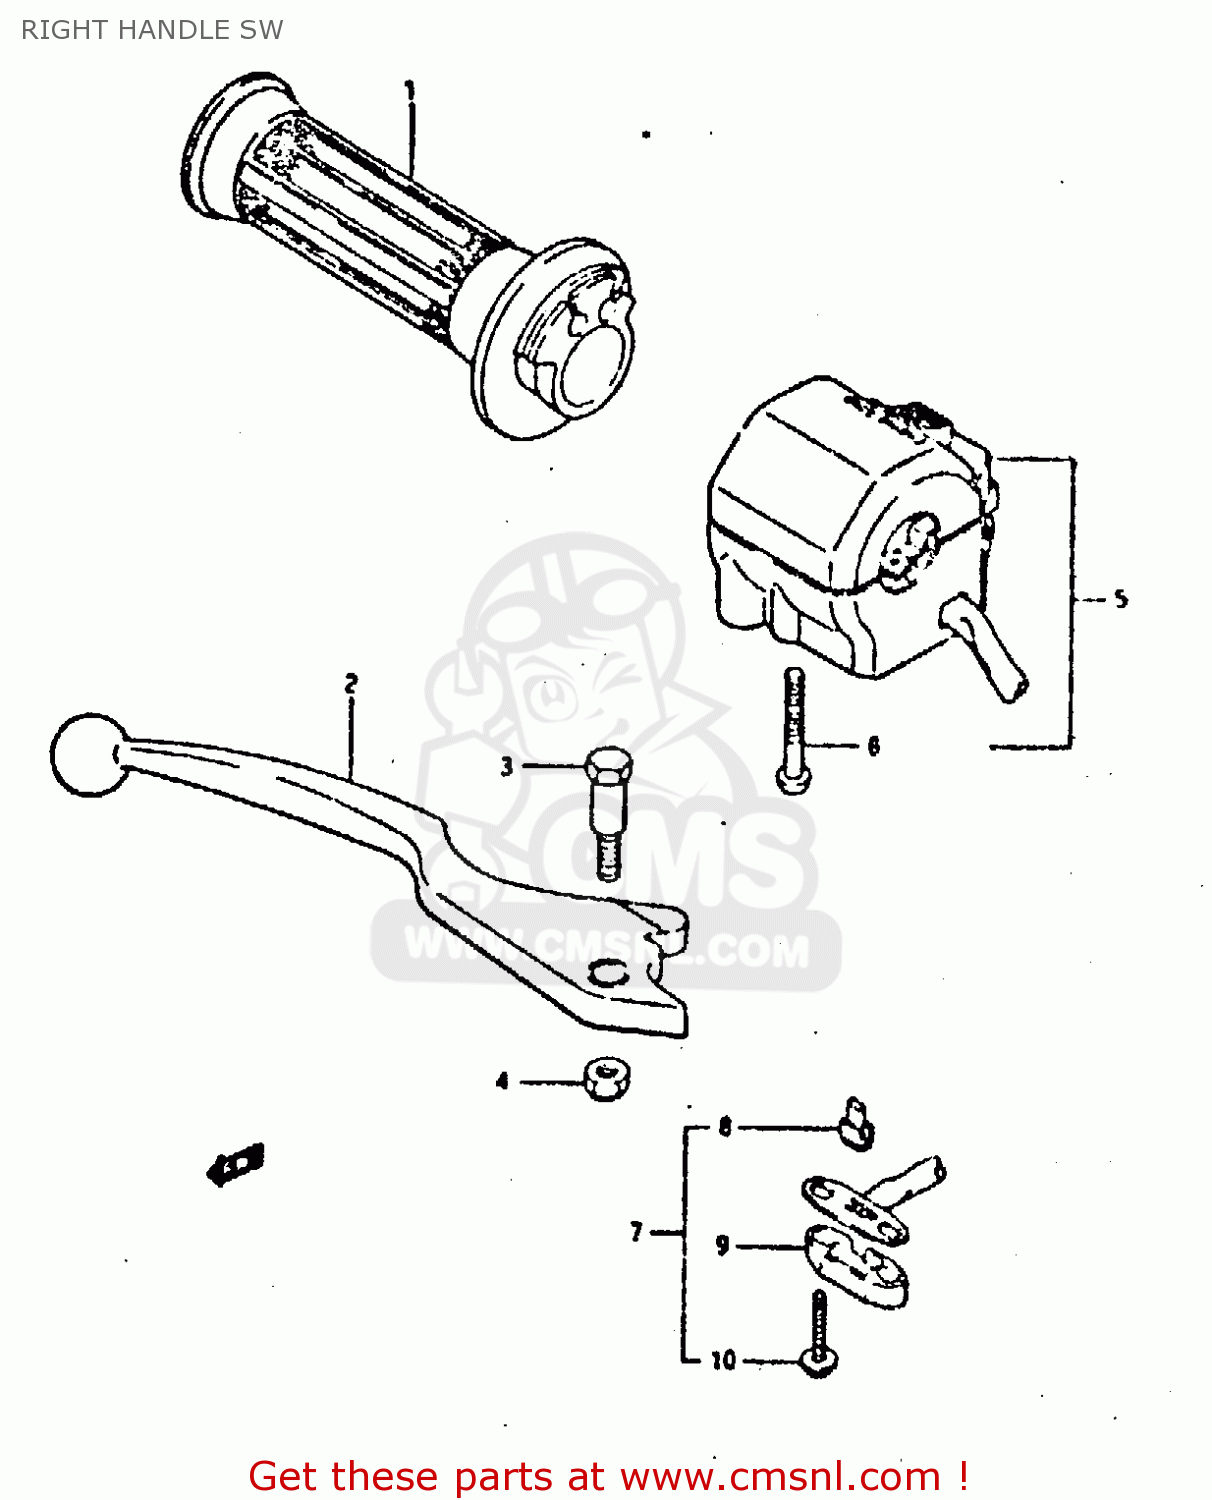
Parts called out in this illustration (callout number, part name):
1	GRIP,THROTTLE
2	LEVER,BRAKE
3	BOLT,LEVER PIVOT
4	NUT
5	SCHAKELAARSET
6	SCREW, 5X45
7	SWITCH ASSEMBLY
8	CONTACT,SWITCH
9	COVER,FR BK TERMINAL BASE
10	SCREW
